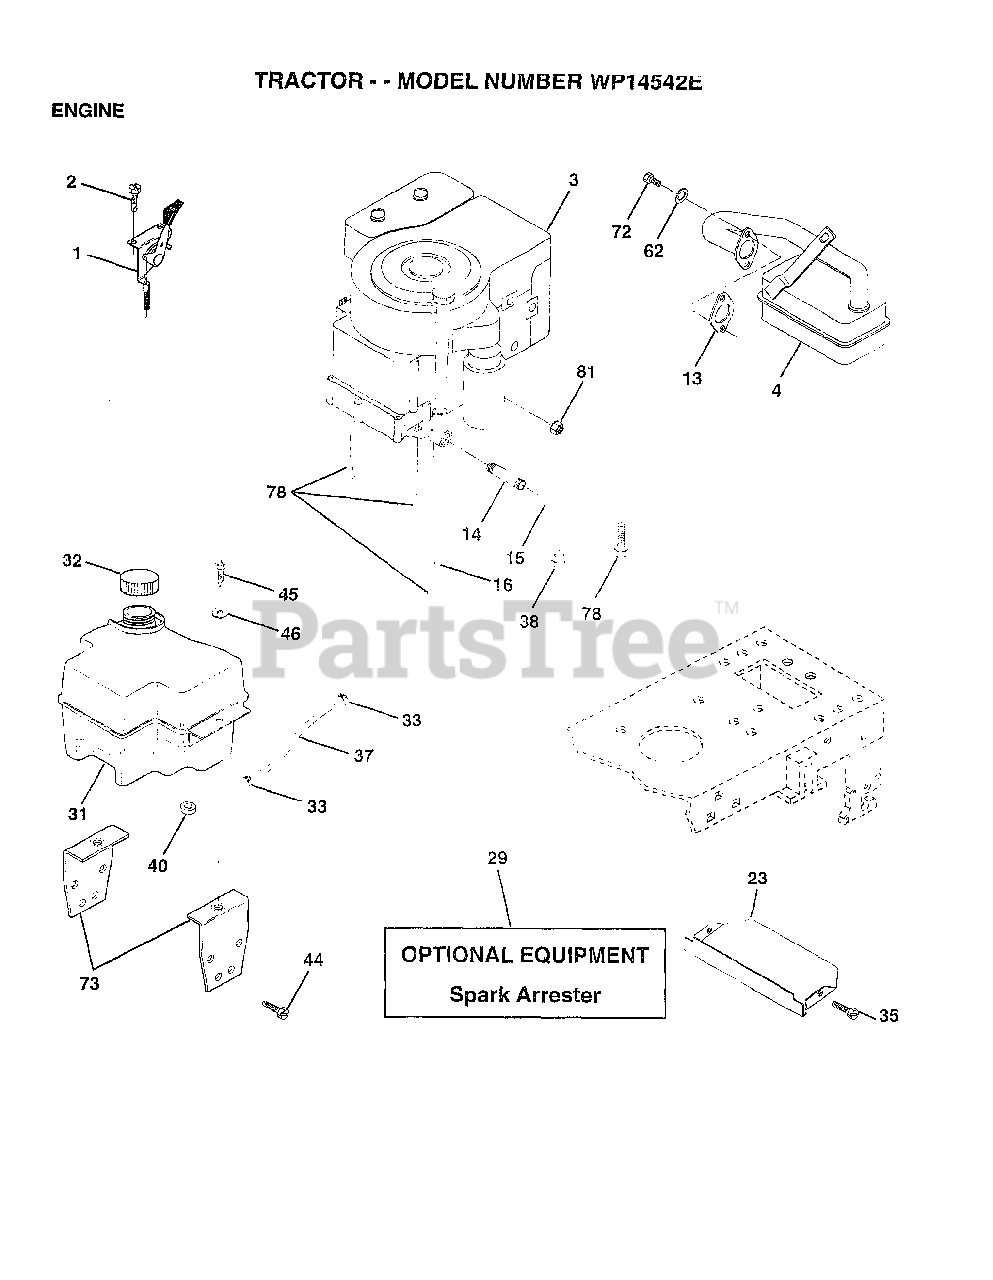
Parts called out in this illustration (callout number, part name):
1	"CONTROL,THROTTLE"
2	SCREW LT
4	MUFFLER
13	GASKET ENG 1 313 LD TIN PLATED
14	PIPE NIPPLE
15	ELBOW
16	LOCKWASHER
23	SHIELD.BRN/DBR.GD
31	TANK.FUEL.FRONT.
32	CAP ASM FUEL
33	HOSE CLAMP
35	SCREW
37	LINE FUEL
44	SCREW
45	SCREW HEX CRT
46	WASHER
62	LOCKWASHER
72	SCREW
73	BRACKET.SUPT.TANK
78	SCREW
81	NUT
